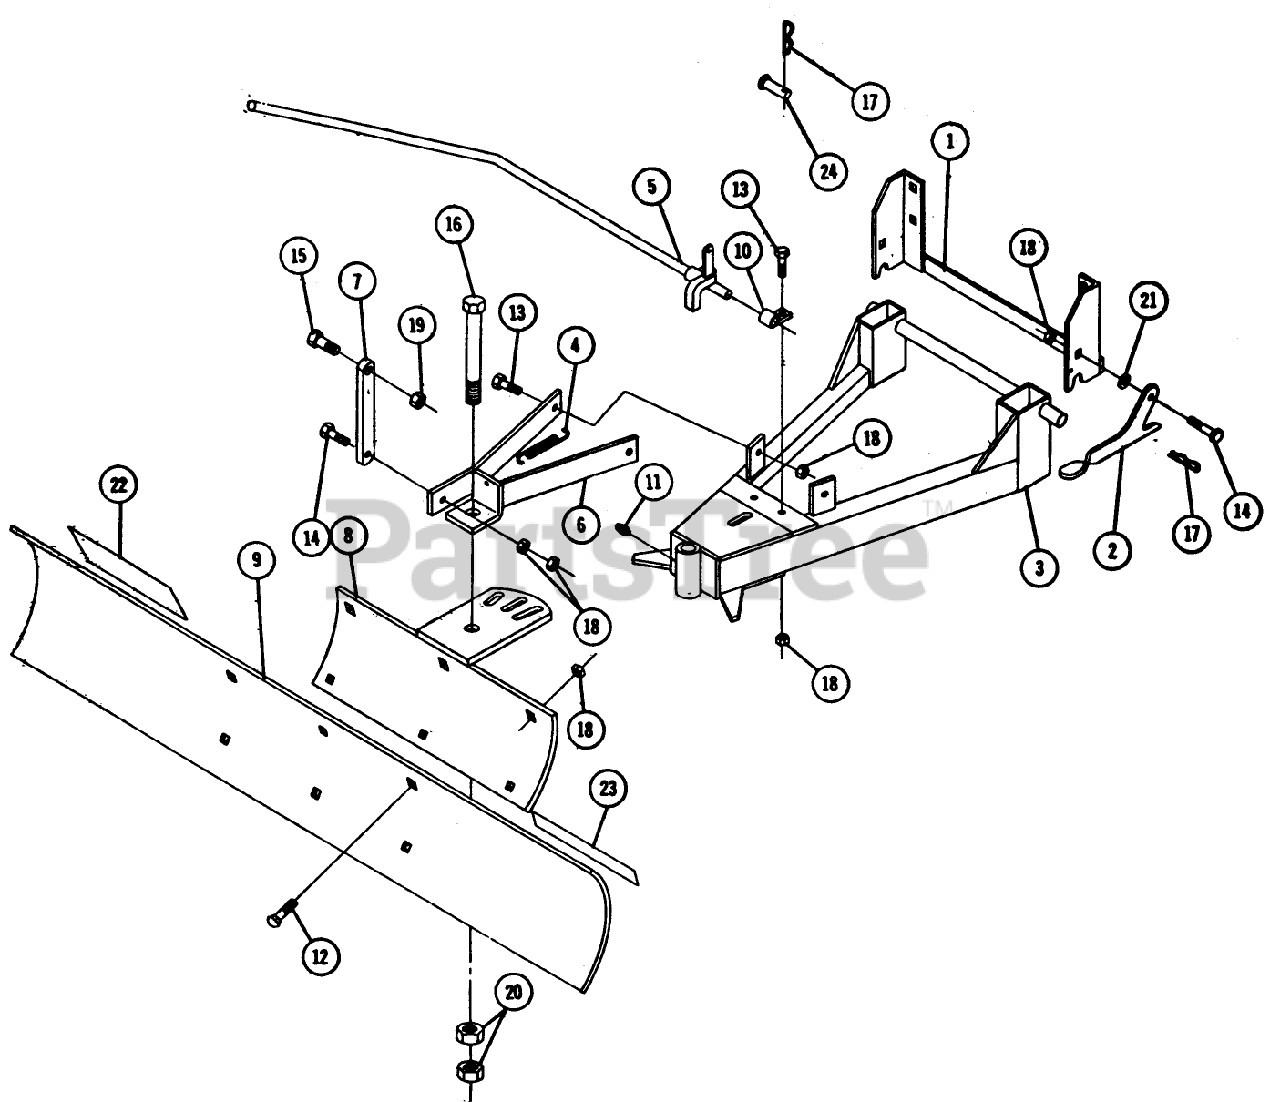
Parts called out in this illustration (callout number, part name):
1	Breather
3	"A" Frame Assembly
12	Bolt 3/8-16 x 1
13	Bolt 3/8-16 x 1
14	Bolt 3/8-16 x 1
15	Bolt 3/8-16 x 1
16	Bolt-Hex 3/4-10 x 5
17	Hairpin
19	Locknut-1/2-13
20	Nut 3/1-10 Jam
21	Washer
24	Pin Clevis
